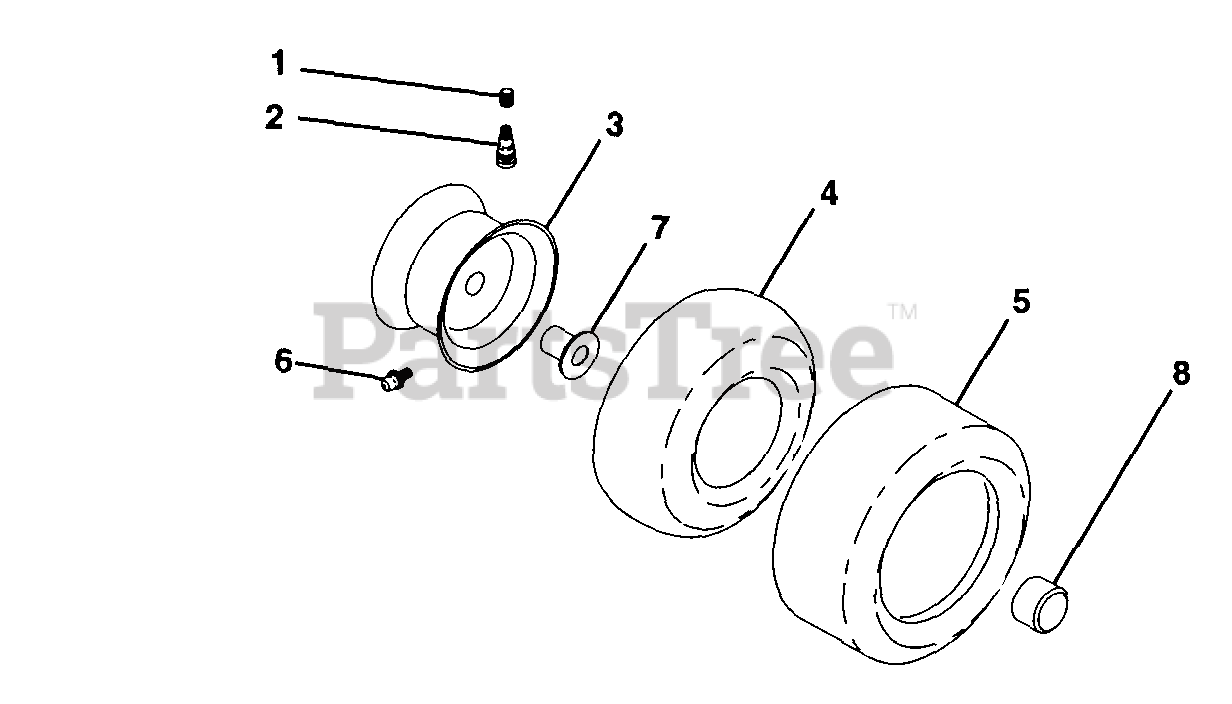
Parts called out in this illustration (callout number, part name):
1	Cap, Valve, Tire
2	Stem, Valve
3	Rim Assembly, Front
3	Rim Assembly, Rear
4	Tube, Front (Service Item Only)
4	Tube, Rear (Service Item Only)
5	Tire, Front
5	Tire, Rear
6	Fitting, Grease
7	Bearing, Flange (Front Wheel Only)
8	Cap, Hub, Axle Blk.
